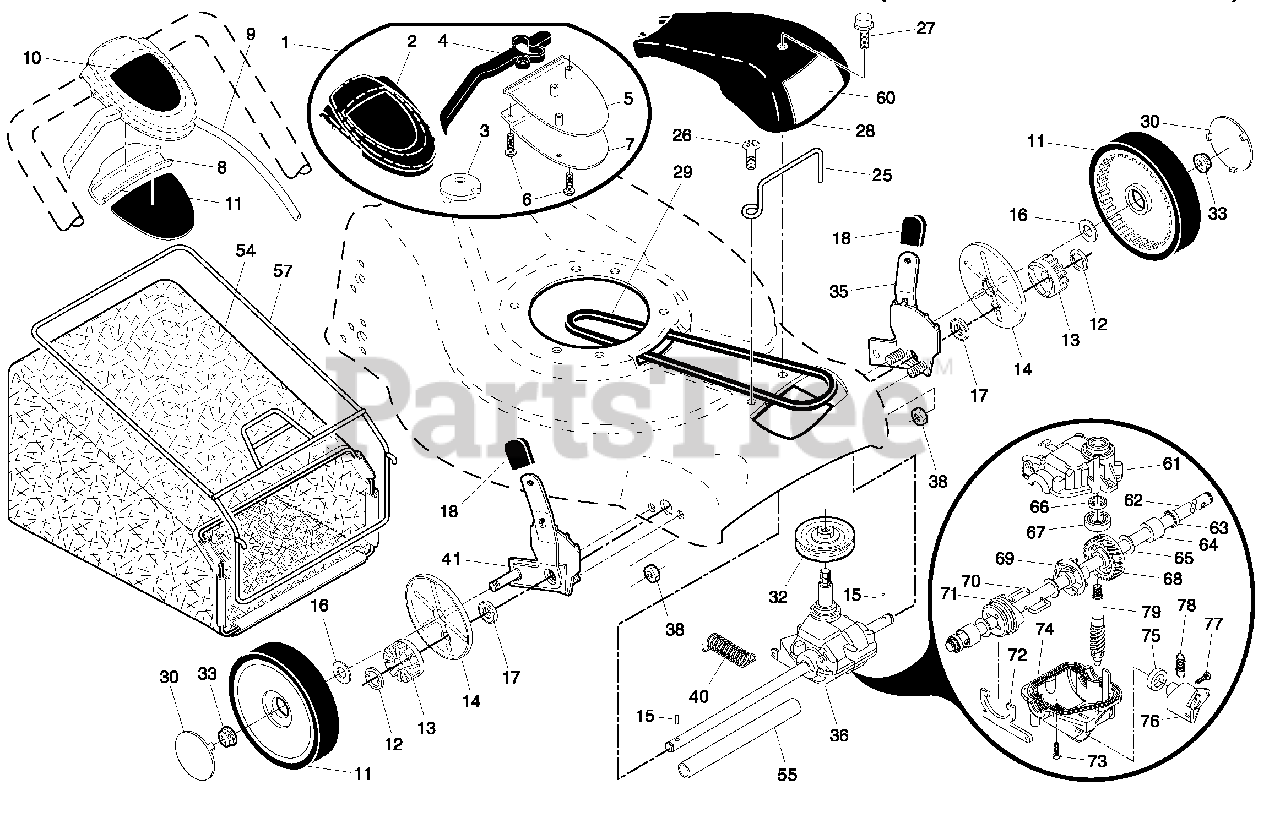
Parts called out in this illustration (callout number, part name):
2	Lower Handle
3	Control Bar
4	Engine Zone Control Cable
5	Handle Bolt
6	Handle Knob
7	Hairpin Cotter
8	Wire Tie
9	Kit, Rear Door
10	Pop Rivet
11	Support Bracket, LH
12	Support Bracket, RH
13	Screw 1/4-20 x 5/8
14	Handle Bracket Assembly, LH
15	Handle Bracket Assembly, RH
16	Spring, Rear Door, LH
17	Spring, Rear Door, RH
18	Keps Locknut 1/4-20
19	Rope Guide
20	Rear Skirt
21	Hinge Screw 1/4-20 x 1-1/4
22	Pulley, Engine
23	Key, Hi-Pro
25	Screw, Hex Head, Threaded, Rolled 3/8-16 x 2
26	Nut, Hex, Flangelock 3/8-16
27	Wheel & Tire Assembly, Rear, 14"
28	Bolt, Shoulder 5/16-18
30	Axle Arm Assembly, Rear, RH
31	Selector Knob
32	Selector Spring
33	Nut, Hex, Nylock 5/16-18
34	Axle Arm Assembly, Rear, LH
35	Hubcap
36	Bolt, Rear Door
37	Thread Cutting Screw w/Sems 5/16-18 x 3/4
38	Washer, Flat .34 x 1.38
40	Mounting Bracket, Debris Shield
41	Screw, Debris Shield
43	Debris Shield
44	Kit, Housing
45	Danger Decal
46	Blade Adapter
47	Blade, 21"
48	Hardened Washer
49	Helical Washer 3/8
50	Blade Bolt, Hex Head, Grade 8
57	Upstop Bracket
58	Screw #10-24 x 1/2
59	Discharge Deflector
60	Hinge Bracket
61	Spring, Torsion
62	Rod, Hinge
63	Nut, Hex
64	Mulcher Door
65	O-Ring
66	Washer, Flat 3/8
67	Kit, Bushing, High Wheel
68	Bushing, Nylon, Black
96	Clip, Cable
96	Operator's Manual, English
96	Operator's Manual, French
96	Repair Parts Manual, English / French
